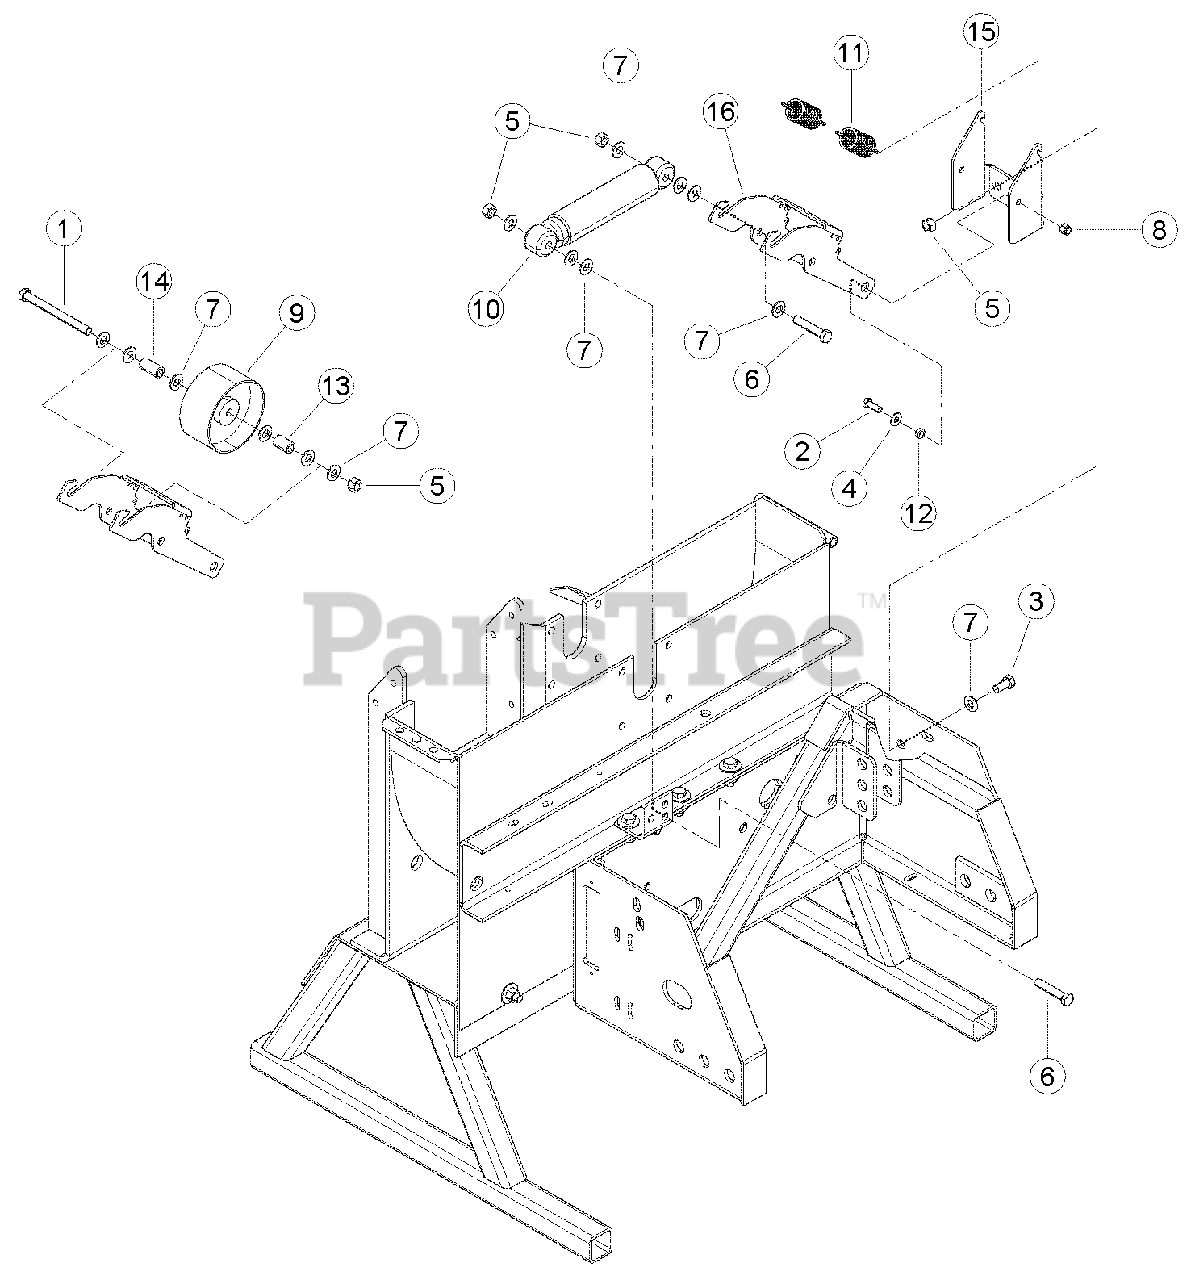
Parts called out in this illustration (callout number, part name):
1	BOLT, 1/2 X 5-1/2 HEX HD GR5 ZP
2	BOLT, 3/8 X 1 HEX HD GR5 ZP
3	BOLT, 1/2 X 1 HEX HD GR5 ZP
4	WASHER, 3/8 FLAT ZP
5	NUT, 1/2 CENTERLOCK GRB ZP
6	BOLT, 1/2 X 2-1/2 HEX HD GR5 ZP
7	WASHER, 1/2 SAE FLAT ZP
8	NUT, 3/8 NE NYLOCK ZP
9	PULLEY, IDLER 5" X 2.50"
10	ABSORBER, IDLER SHOCK
11	SPRING, 1.25 OD X 3.50 LG X .148 WD
12	SPACER IDLER PIVOT
13	SPACER, .75 X 1.18
14	SPACER, .75 X 1.47
15	BRACKET, INSIDE IDLER MOUNTING
16	ARM, INSIDE IDLER
